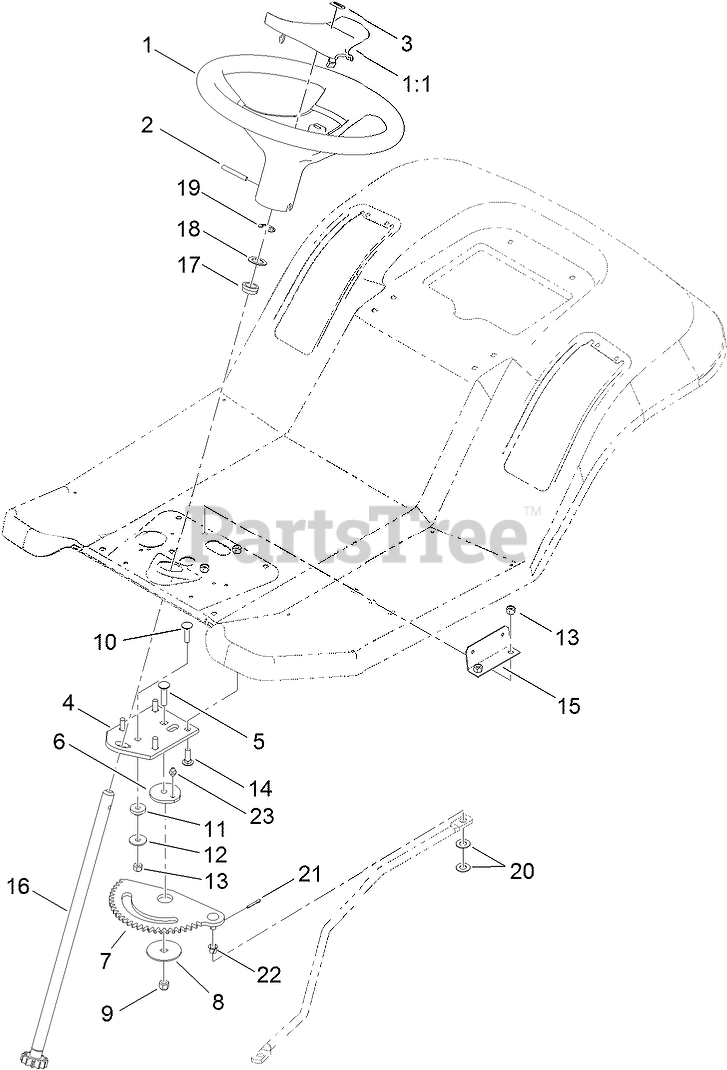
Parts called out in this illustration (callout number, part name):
1	STEERING WHEEL ASM
1:1	COVER-WHEEL, STEERING
2	PIN-ROLL
3	DECAL
4	BRACKET-RACK, STEERING
5	SCREW-CARR
6	BUSHING-ECCENTRIC
7	RACK-STEERING
8	WASHER-BEARING
9	NUT-LOCK, NI
10	SCREW-CARR
11	SPACER-RACK, STEERING
12	WASHER-PIVOT
13	NUT-LOCK, NI
14	BOLT-CARR
15	BRACKET-MODULE
16	SHAFT-STEERING, LONG
17	BEARING-FLANGE
18	WASHER-THRUST
19	E-RING
20	WASHER-FLAT
21	PIN-COTTER
22	BUSHING-FLANGED, NYLON
23	FITTING-GREASE
